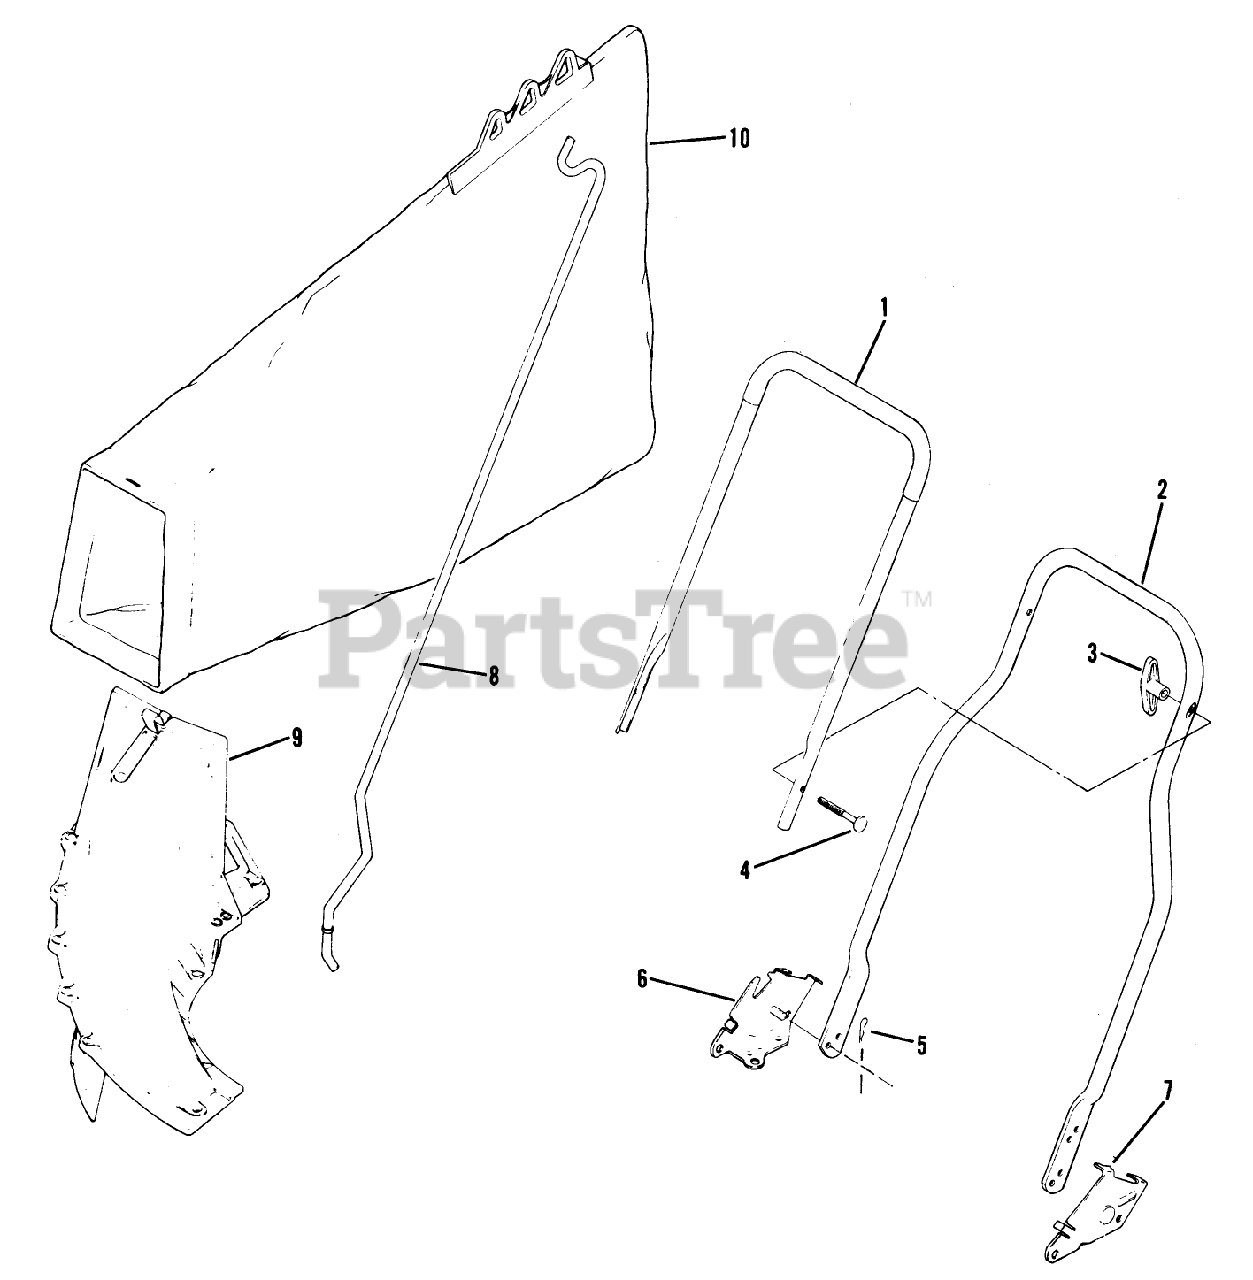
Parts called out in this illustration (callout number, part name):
3	NUT-WING
5	HAIR PIN
8	ROD GRASSBAG
10	89802 LB WHOLE GOODS
